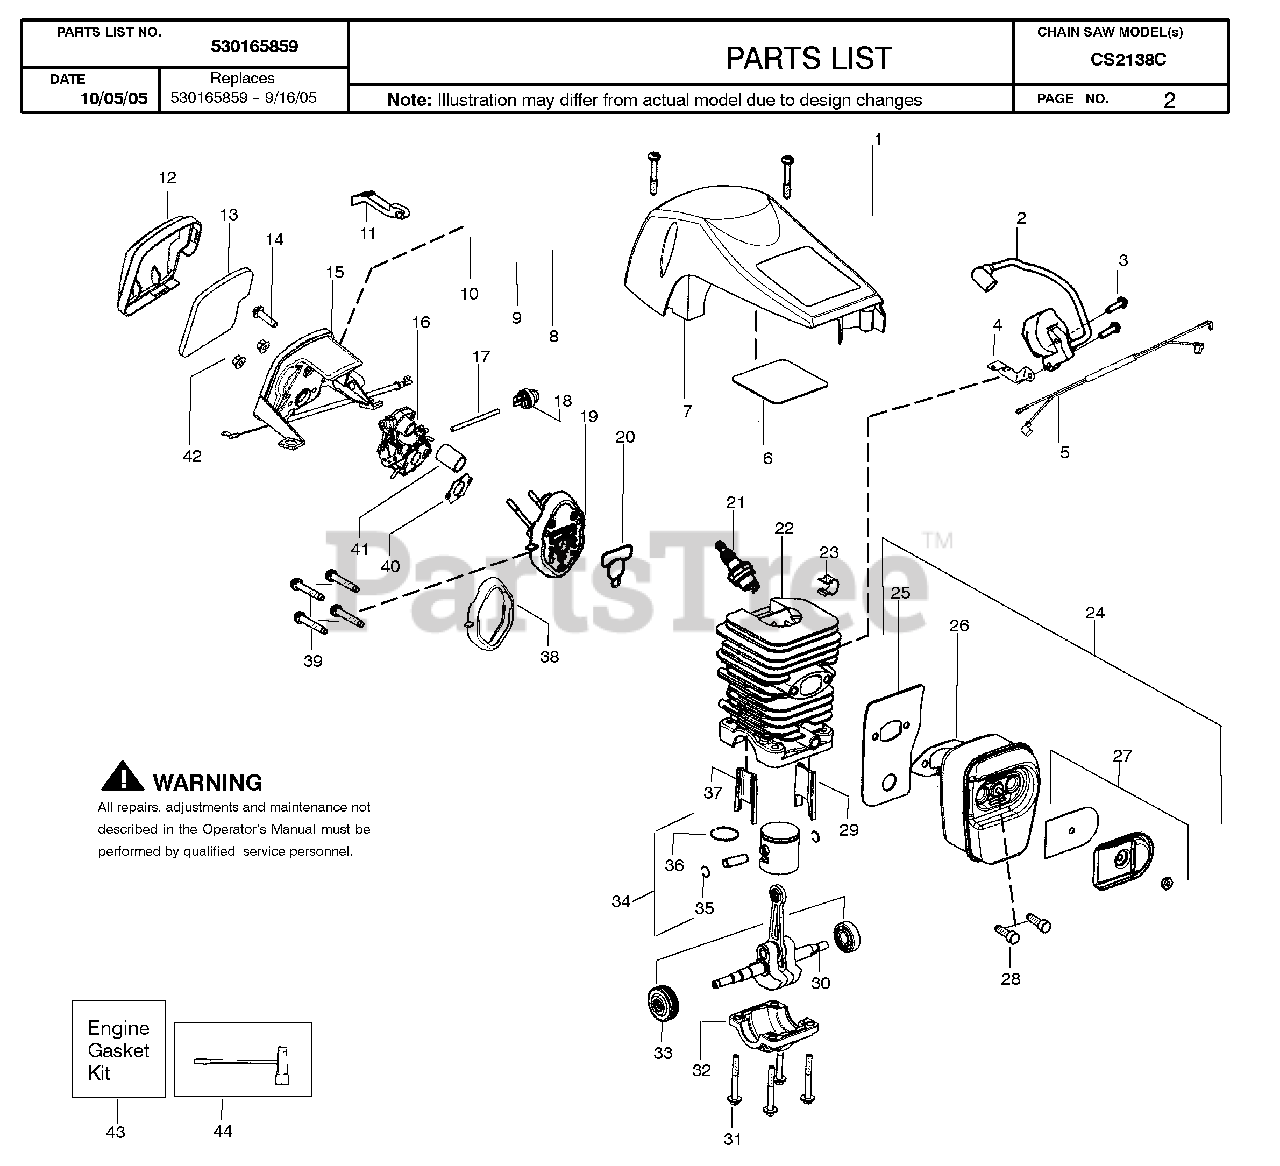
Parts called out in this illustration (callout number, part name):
3	SCREW M5.38-14X22.225MM
4	STRAP GROUND
5	ASSY WIRE HARNESS
7	HOUSING CYLINDER SHIELD
9	LEVER IGNITION SWITCH
10	SPRING IGNITION SWITCH
11	LEVER CHOKE
12	COVER AIR FILTER
13	FILTER AIR
14	SCREW M5-0.8X16
18	AIR PURGE
19	KIT CARB ADAPTOR
20	KIT GASKET SAS
21	SPARK PLUG (RCJ-7Y)
22	KIT CYLINDER
23	HIGH TENSION LEAD CLIP
24	KIT MUFFLER
25	PLATE BACK MUFFLER
26	KIT GASKET SAS
27	KIT SPARK ARRESTOR
28	SCREW MUFFLER
29	INSERT TRANSFER PORT LEFT
30	ASSY CRANKSHAFT AND ROD
31	BOLT M6-1.0 X 25MM
32	CRANKCASE CASTING
33	BEARING & SEAL ASSEMBLY
34	KIT PISTON
35	C-CLIP,PSTN PIN 36/41
36	RING-PISTON
37	INSERT TRANSFER PORT RIGHT
38	KIT GASKET SAS
39	SCREW M5-0.8X30MM
40	KIT GASKET SAS
41	TUBE INTAKE
43	KIT GASKET SAS
44	SCRENCH
